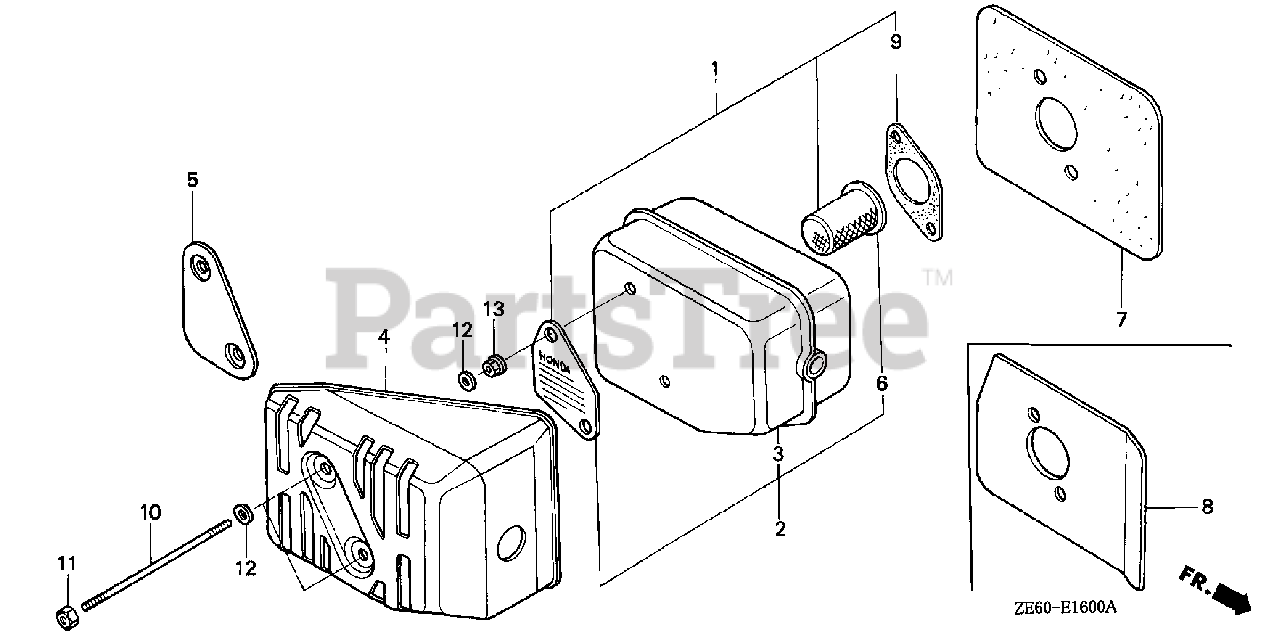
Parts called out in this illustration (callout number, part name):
1	ARRESTER KIT, SPARK
2	MUFFLER (NOT AVAILABLE)
4	PROTECTOR, MUFFLER
6	ARRESTER KIT, SPARK
7	GASKET, MUFFLER
9	GASKET, MUFFLER
10	BOLT, STUD (6X81)
11	NUT, SELF-LOCK (6MM)
